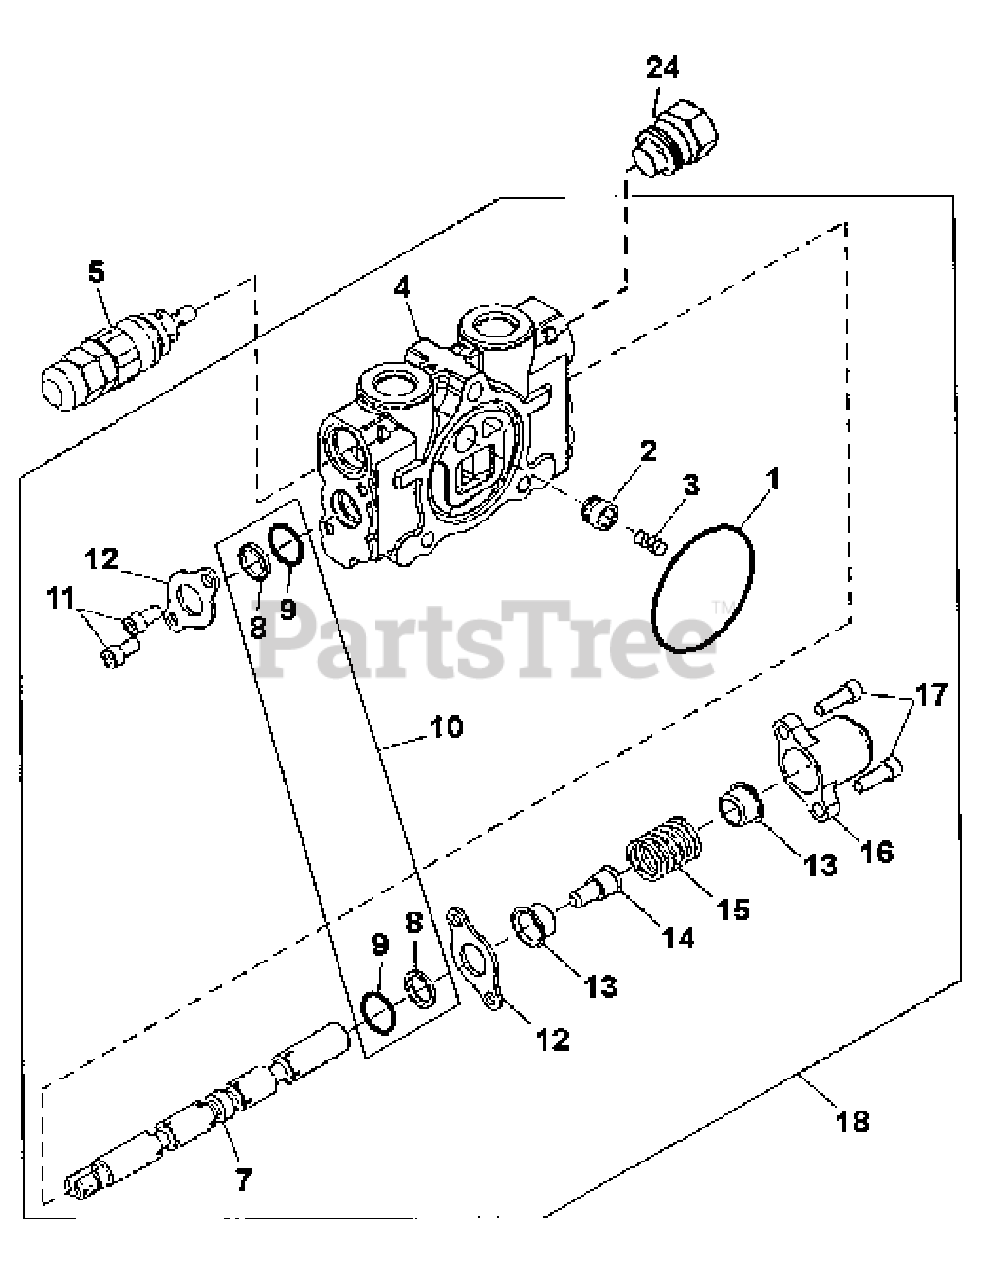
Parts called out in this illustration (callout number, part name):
1	O-RING
2	POPPET, LOAD CHECK
3	SPRING, LOAD CHECK
4	VALVE SECTION
5	RELIEF, WORK PORT 2650PSI
8	WIPER, SPOOL
9	O-RING SPOOL
10	SEAL KIT, MINOR
11	CAP SCREWS, SOCKET HEAD
12	PLATE, RETAINER
13	SEAT, SPRING
14	SCREW, SPRING SEAT
15	SPRING, SPOOL CENTERING
16	CAP, SPRING SPOOL
17	CAP SCREWS, SOCKET HEAD
18	VALVE SECTION ASSEMBLY
24	PLUG, SHUT OFF
